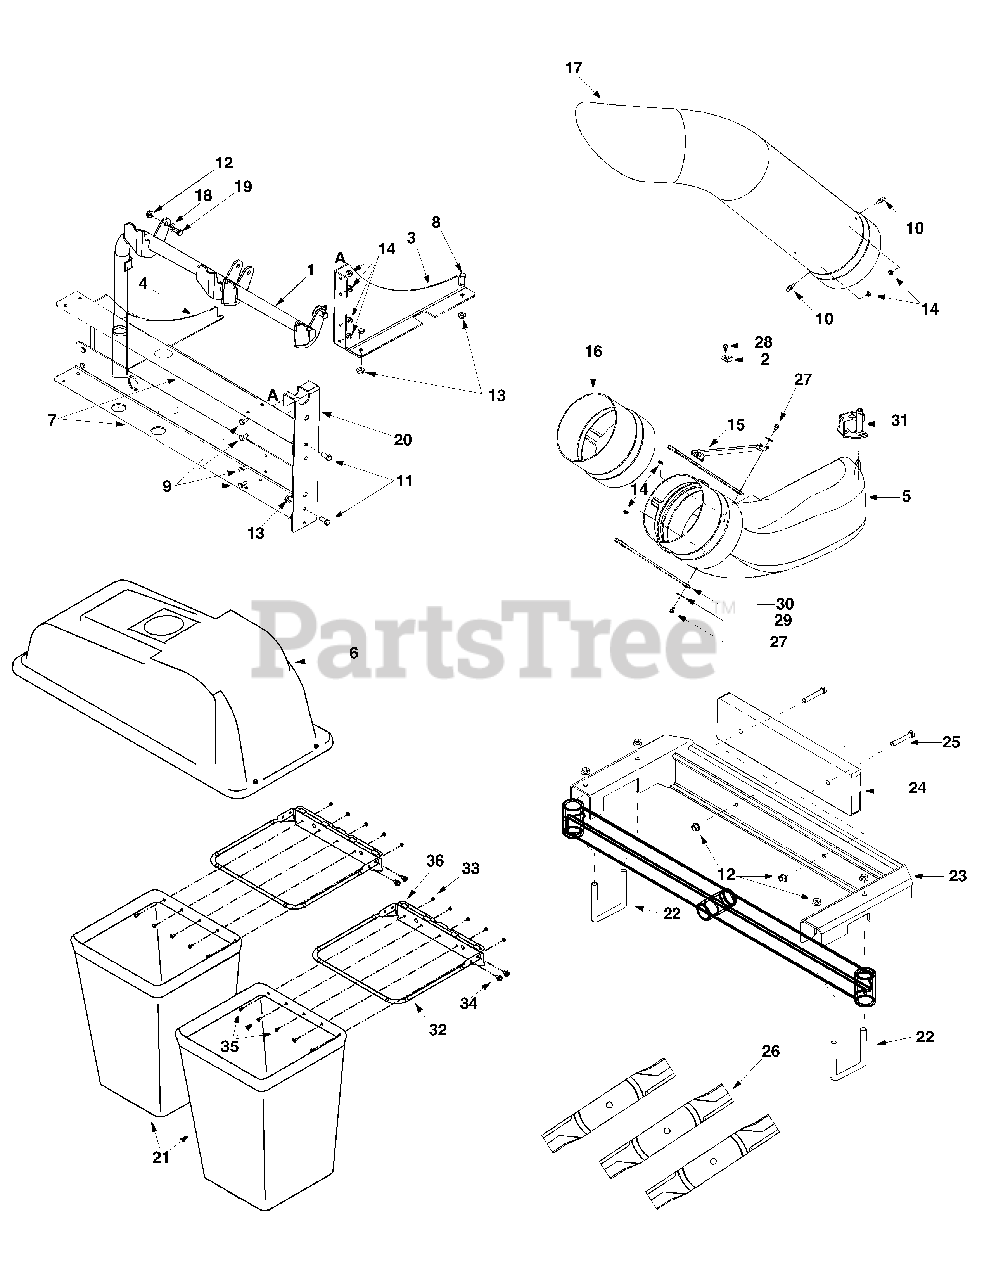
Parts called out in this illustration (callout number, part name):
2	Retainer Hook Bracket
5	Elbow Chute Assembly
6	Grass Catcher Cover
8	Hex Bolt 5/16-18 x 2.75"
9	SCREW 1/4-20 x .620 GR5
10	Grass Catcher Pin 1/4-20
11	SCREW 5/16-18 x .75 GR5
12	HEX LOCK NUT
13	HEX FLANGE NUT
14	Hex Flange Lock Nut 1/4-20
15	Retainer Strap Assembly
16	8" Extension Chute
17	8" Catcher Tube
18	Belleville Washer
19	Shoulder Screw 3/8-16
21	Grass Bag
22	U Bolt 3/8-16 x 1.50"
25	Hex Bolt 3/8-16 x 2.25"
26	Blade 17.9 x .756
27	SCREW 1/4-20 X1.00 GR5
28	Hex Screw 1/4-20
29	Flat Washer
30	Chute Strap
35	Machine Screw
